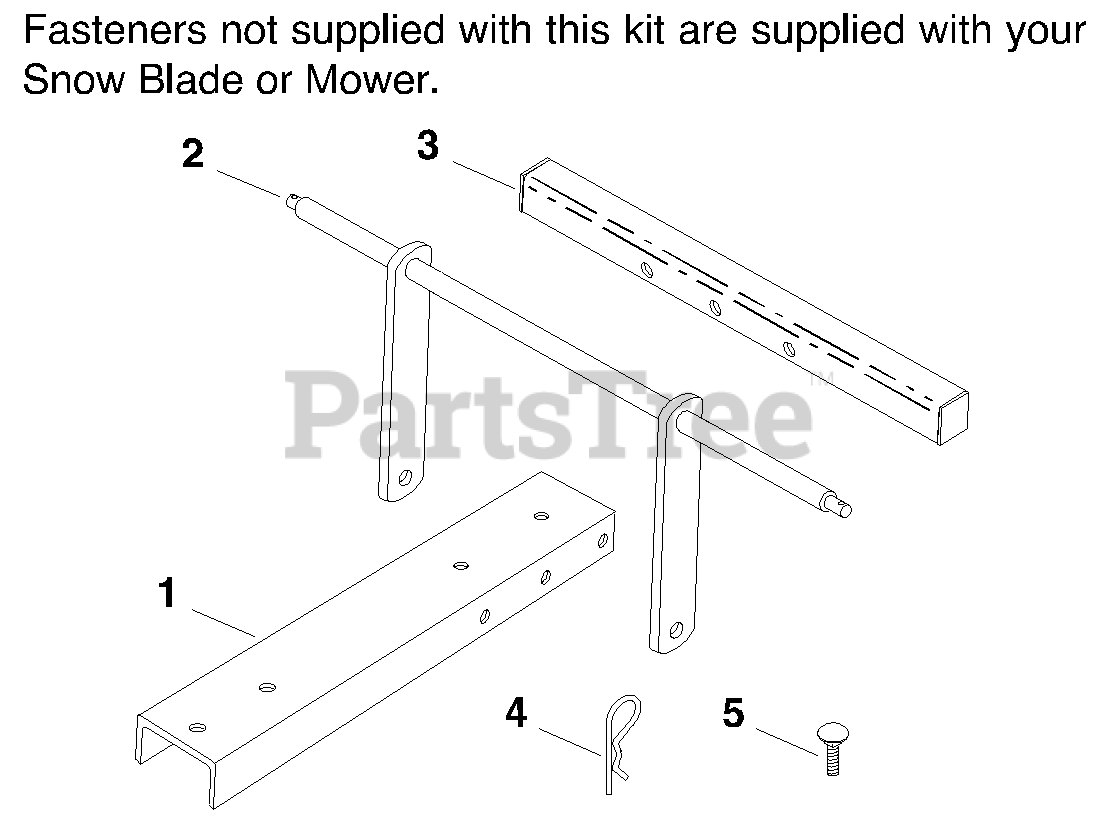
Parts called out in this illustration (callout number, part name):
1	Rear Push Bar
2	Lift Assembly
3	Guide Bracket Mounting Assem.
4	Hairpin Cotter, 5/32"
5	Carriage Bolt, 3/8-16 x 7/8"
